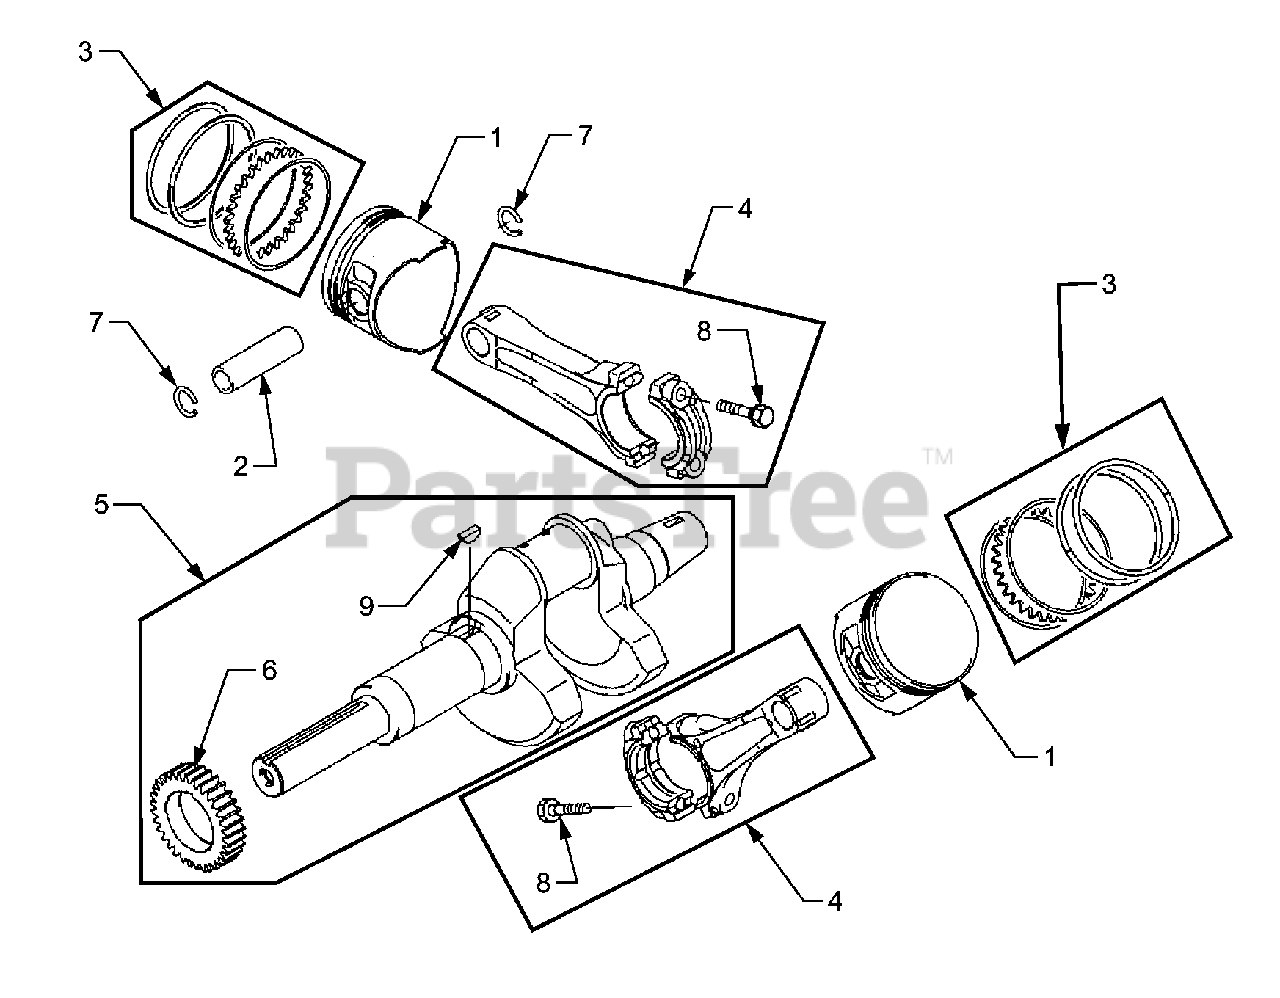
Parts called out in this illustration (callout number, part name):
3	Ring Set, Piston
4	Rod, Connecting
5	Crankshaft Assembly
6	Gear, Spur, 33T
9	Key, Woodruff
